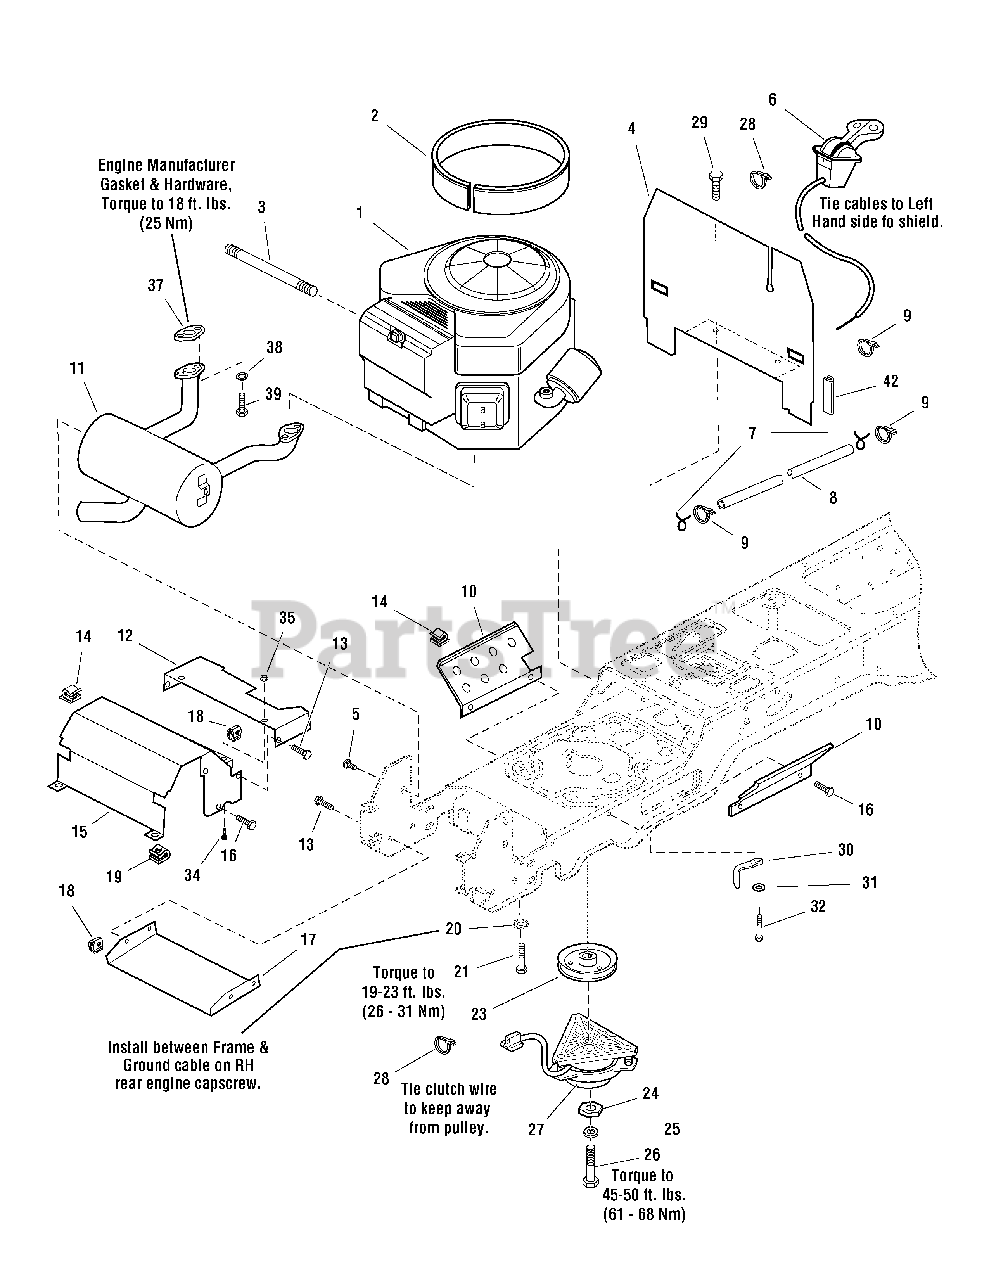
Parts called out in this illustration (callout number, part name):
1	* ENGINE, 20 HP Briggs & Stratton Vanguard Twin
1	* ENGINE, 22 HP Briggs & Stratton INTEK Twin
1	* ENGINE, 24 HP Briggs & Stratton INTEK Twin
1	* ENGINE, 24 HP Briggs & Stratton Twin
2	EDGING, Airduct
3	HOSE, Oil Drain
4	HEAT SHIELD
5	CAPSCREW, Hex Head, Taptite, 5/16-18 x 1/2
6	THROTTLE CONTROL
7	CLAMP, Hose, Wire
8	HOSE, Fuel
9	TIE, Self Locking, 7-5/16 Long
10	SHIELD, Side, Heat
11	MUFFLER ASSEMBLY
12	DUCT, Muffler Extension
13	CAPSCREW, Hex, Whiz Lock, 1/4-20 x 5/8
14	CLIP, Wire
15	DUCT, Muffler Top
16	CAPSCREW, Hex Head Taptite, 1/4-20 x 3/8
17	SHIELD, Muffler Bottom
18	NUT, Speed, 1/4-20
19	NUT, Speed, 3/8-18
20	WASHER, Locking, External Teeth, 3/8
21	CAPSCREW, Hex Head, Taptite, 3/8-16 x 1-1/2
23	PULLEY, Engine
24	WASHER, Hex, 7/16 x 1-1/2
25	WASHER, Locking, 7/16
26	CAPSCREW, Hex Head 7/16-20 x 3-1/2
27	CLUTCH
28	TIE, Self Locking
29	CAPSCREW, Hex Head Taptite, 1/4-20 x 1/2
30	RETAINER, Clutch
31	WASHER, Flat, 3/8
32	CAPSCREW, Hex Head 3/8-16 x 1
37	* GASKET
38	LOCKWASHER, 5/16
39	CAPSCREW, Socket Head, 5/16-18 x 7/8, G8
42	EDGING, Rubber
